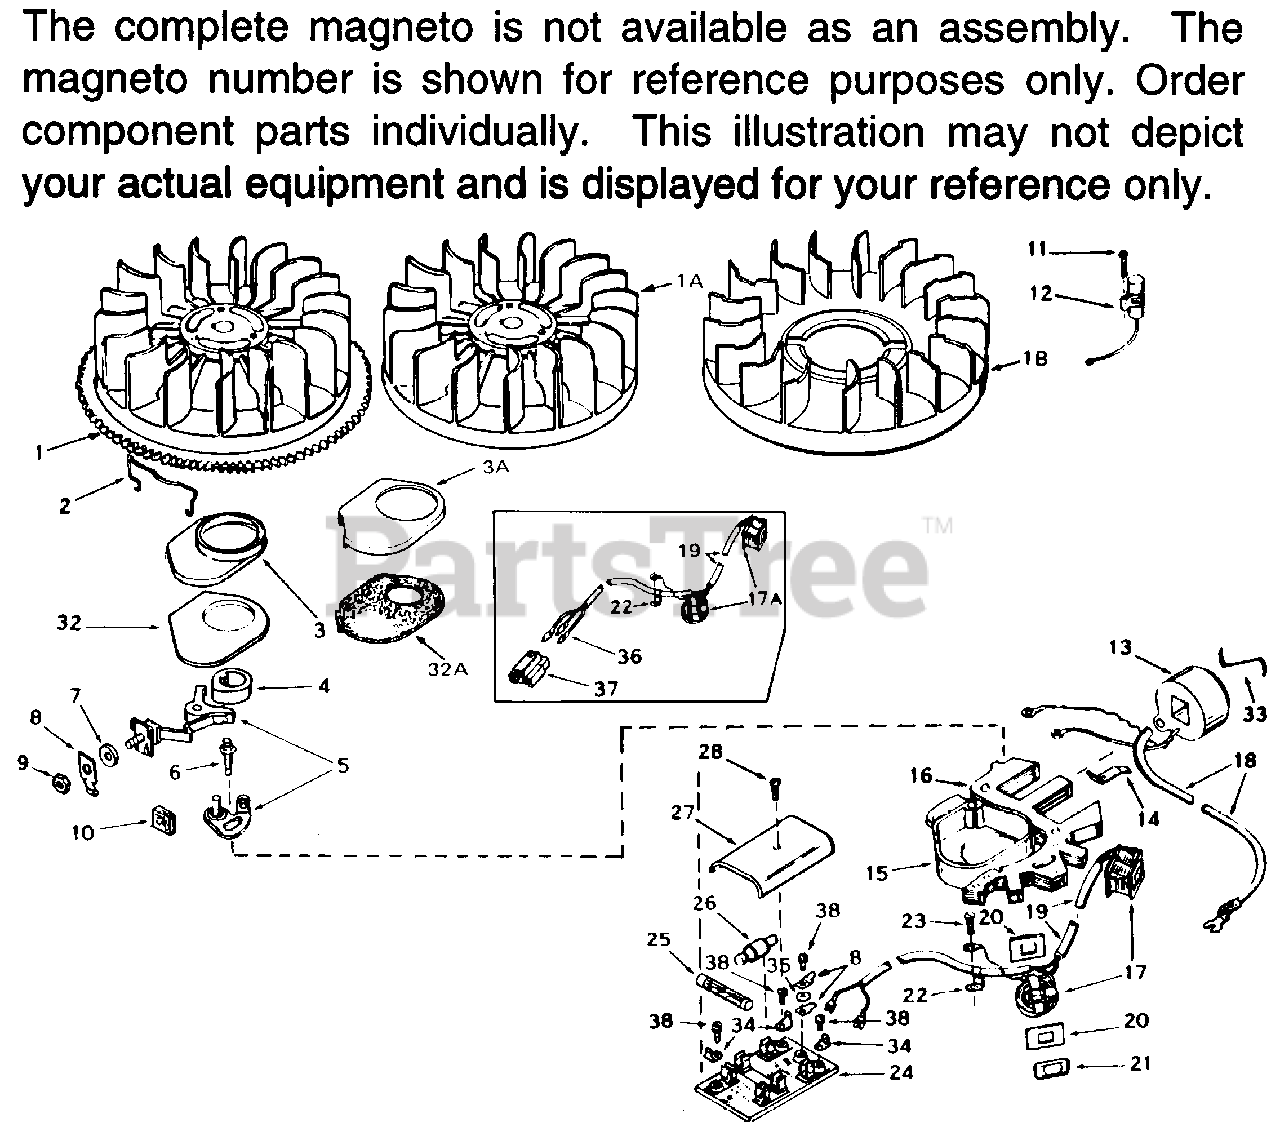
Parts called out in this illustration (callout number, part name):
1	Flywheel
2	Spring, Dust cover
3	Cover, Dust (Early Style)
3A	Cover, Dust (Late Style)
4	Cam, Breaker
5	Breaker Points (also available in Pac kaged Part #740037B)
6	Screw & Lockwasher
7	Washer, Terminal
8	Tab Terminal
9	Nut Terminal
10	Felt, Cam wiper
11	Screw, Condenser fastening
12	Condenser
13	Coil (Incl. 18)
15	Stator Plate Assy. Incl. 2, 3, 5 thru 28, 32, 32A & 33
16	Core & Plate Group
17	Generating Coils & Leads
18	Wire, Lead No. 31616 shielded wire av ailable separately
19	sleeve, Insulation
20	Shield, Coil
21	Clip, Coil fastening
22	Clip, Ground
23	Screw, Ground terminal
24	Plate, Rectifier Incl. 8, 34, 35 & 3 8
25	Fuse (6 Amp)
26	Rectifier
27	Cover, Rectifier panel
28	Screw, 5-40 x 3/8"
32	Gasket, Dust cover (Early Style)
32A	Gasket, Dust cover (Late Style)
33	Clip, Coil locking
34	Tab, Terminal
35	Flat, Washer
38	Screw, 6-32 x 5/16"
